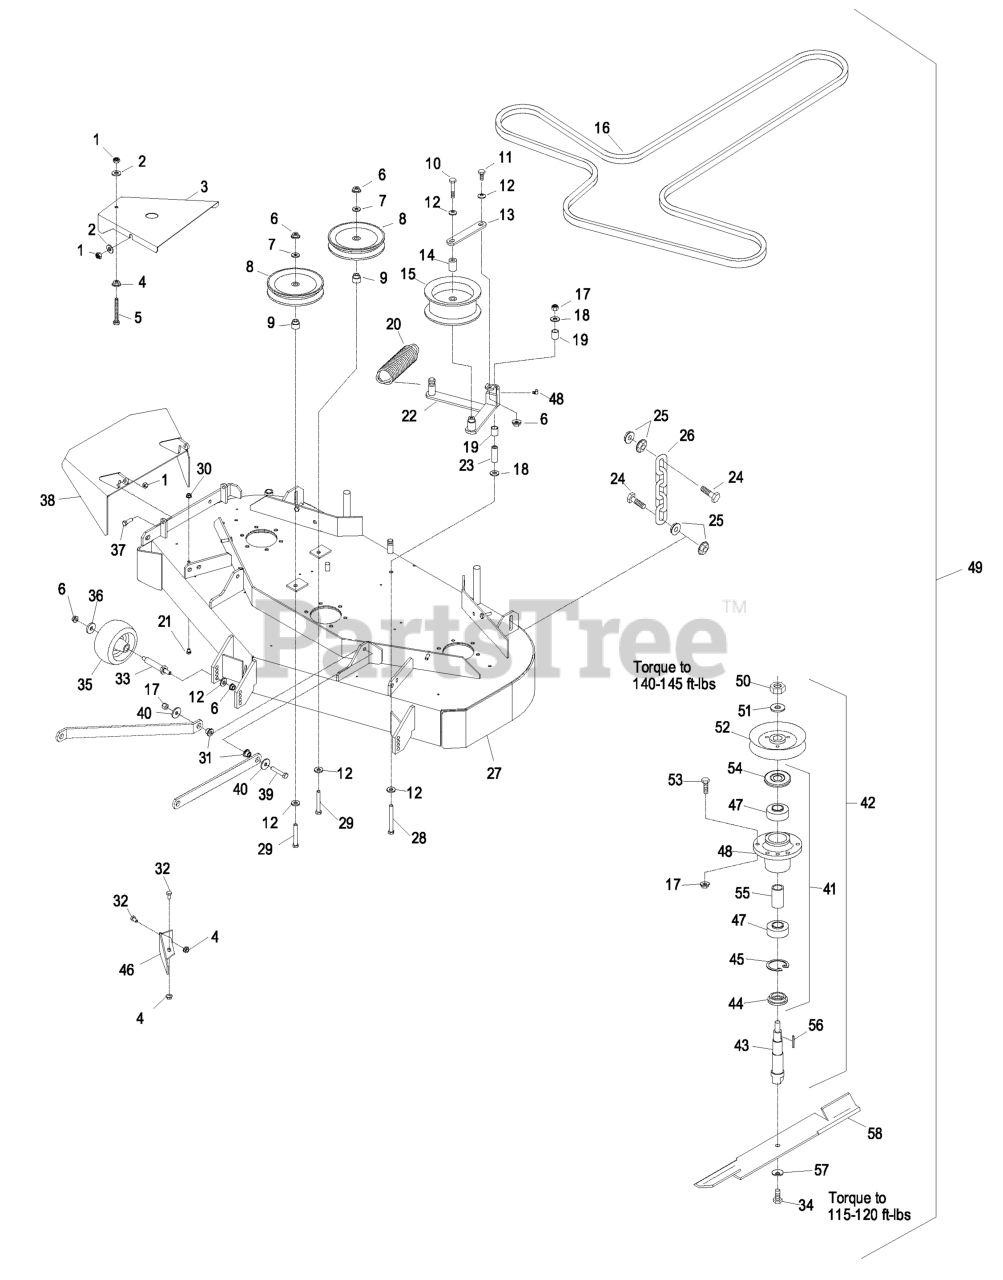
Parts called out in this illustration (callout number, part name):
1	NUT-LOCK, NI
2	WASHER-FLAT
3	SHIELD,BELT
5	BOLT,TAP HH
6	NUT-HHF, WHIZ
7	WASHER-FLAT
8	PULLEY-IDLER
9	BUSHING-IDLER
10	SCREW-HH
11	SCREW-HH
12	WASHER-BELLEVILLE
16	BELT,DECK DRIVE
17	NUT-LOCK, NI
18	WASHER-HARDENED
19	SLEEVE-BEARING
21	SCREW-HH
23	BUSHING-PIVOT, IDLER
24	SCREW-CAP, HH
26	CHAIN-LIFT, DECK
27	ASM,DECK W/DECALS LCT48
28	SCREW-HH
29	SCREW-HH
31	SPACER-STRUT
32	SCREW-HH
34	SCREW-CAP
35	ROLLER-SCALP, ANTI
37	SCREW-HH
38	WLD,CHUTE 48
39	SCREW-HH
43	SPINDLE,SHAFT
44	SPACER-GUARD, BOTTOM
45	RING-SNAP
47	BEARING-JACKSHAFT
49	Deck Complete Service (44")
52	SHEAVE,W/HUB
53	SCREW-HH
54	GUARD-BEARING, TOP
55	SPACER-BEARING
56	KEY-RECTANGLE
57	WASHER-SPRING
